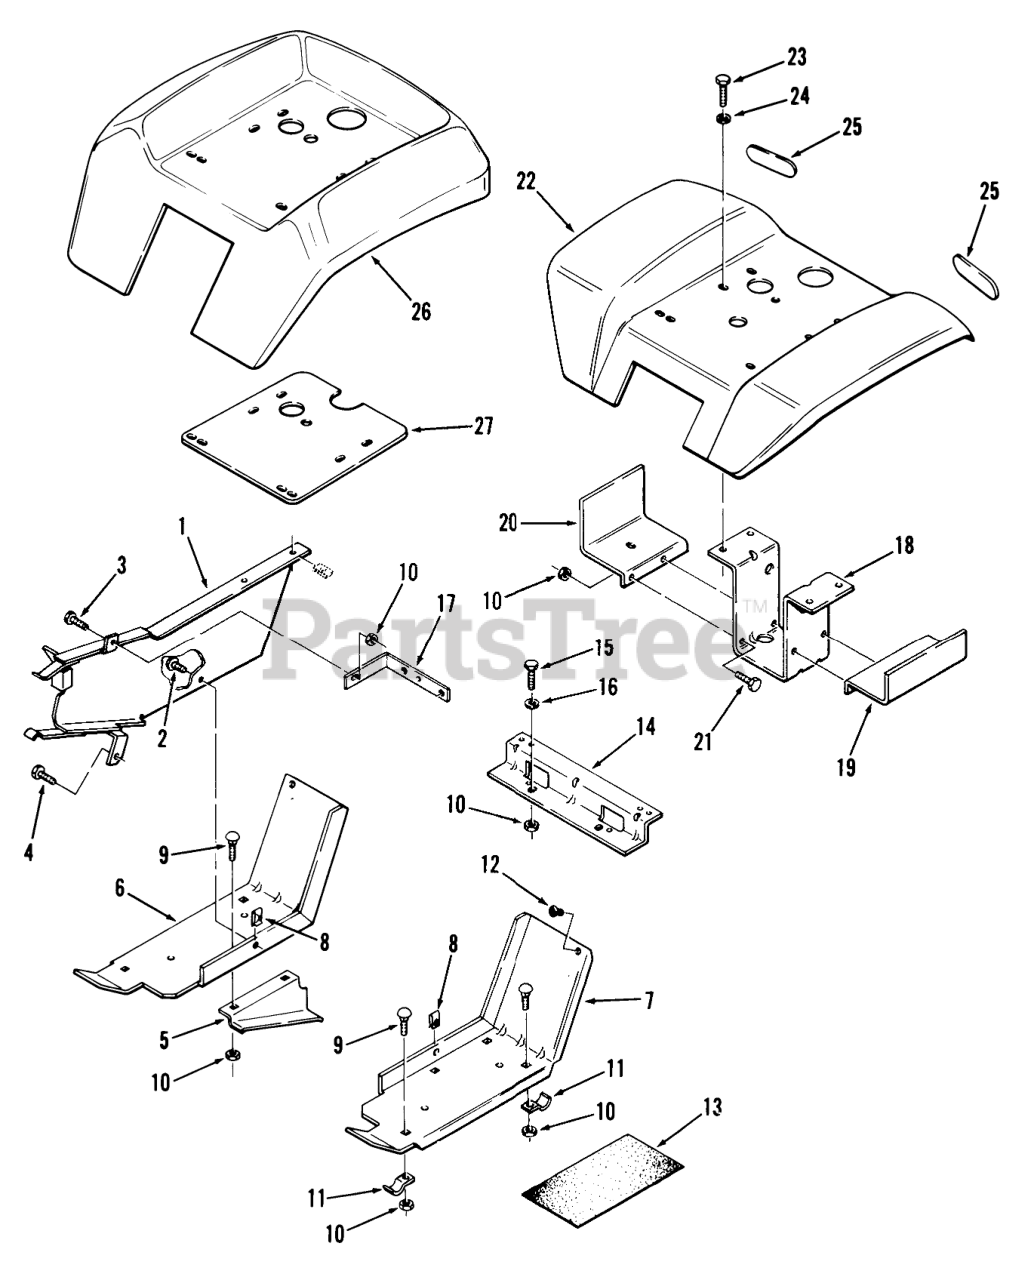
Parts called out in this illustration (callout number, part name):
4	SCREW
7	FOOTREST LH *R
8	Speed Nut
9	CARRIAGE BOLT -4
11	BRACKET
12	BUMPER-RUBBER
13	PAD-FOOTREST
16	WASHER 5/16 SAE
24	WASHER 5/16 SAE
